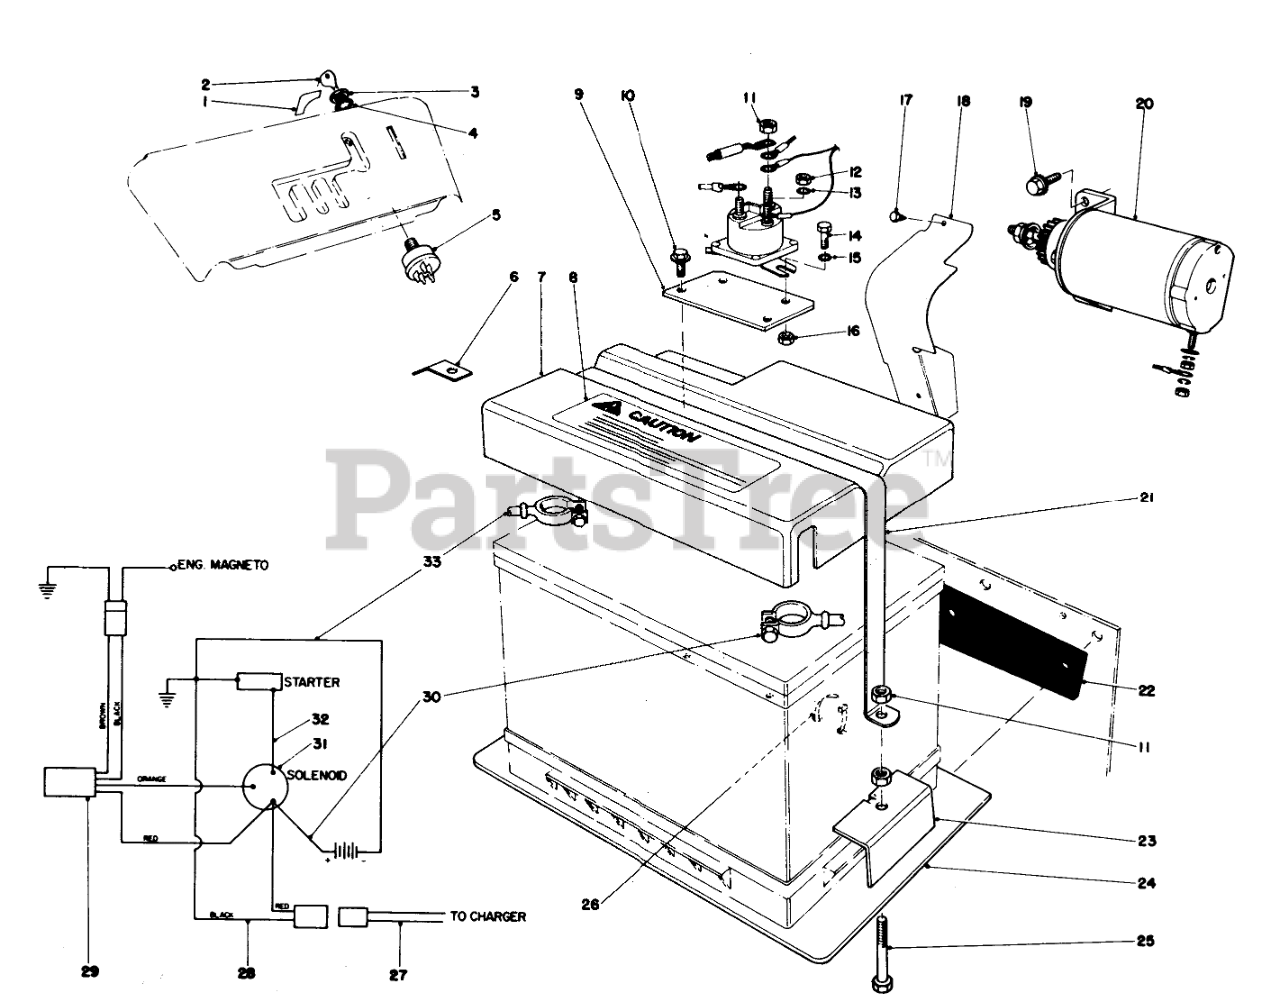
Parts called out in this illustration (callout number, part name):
1	Decal Switch
3	NUT-HH
4	WASHER-TOOTH, INTERNAL
5	SWITCH-STARTER
6	Bracken Wire Clamp
7	Battery Cover (Incl. Ref. #8)
8	Decal-Caution
9	Bracket Solenoid
10	Screw
11	NUT-HEX
12	NUT-HEX
13	WASHER-LOCK, INT
14	SCREW-HH
15	WASHER-LOCK/EXT
16	NUT-LOCK, NI
17	Hex Hd. Sems Screw
18	Pinion Shield
19	Screw-HH
20	Starter Motor & Pinion Assy.
21	Strap Battery
22	Batery Isolation Pad
23	BATTERY CLAMP
24	Battery Mounting Plate
25	SCREW-HH
26	TIE-CABLE
27	MALE WIRE ASM
28	FEMALE WIRE ASM
29	12 V IGN WIRE HARNESS
30	BATT-SOLENOID CABLE
31	SOLENOID
32	STRT MTR-SOLNOID WIRE
33	BATT-GROUND CABLE
